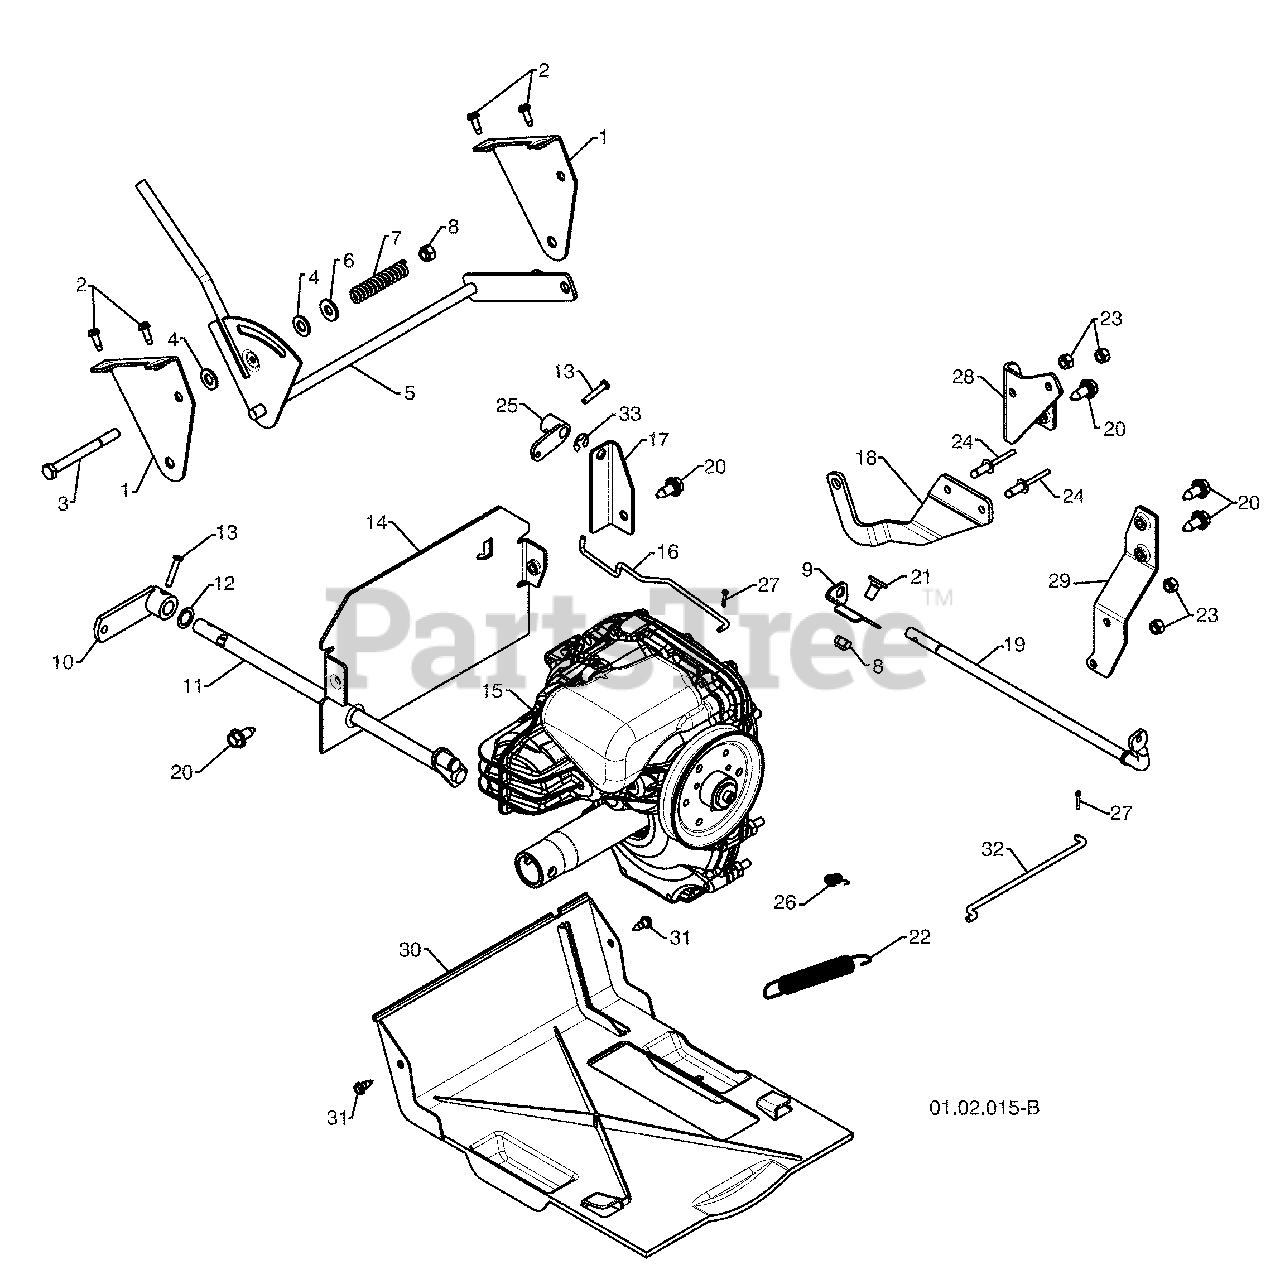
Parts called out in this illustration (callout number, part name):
1	SHIFT BRACKET
2	SCREW 10-24 X .625
3	SCREW 5/16-18 X 3.25
4	PLASTIC WASHER
5	SHIFT ASSEMBLY
7	FRICTION SPRING
8	NUT 5/16-18
9	FRONT CLUTCH BRACKET
10	CONTROL ARM
11	CONTROL SHAFT
13	CLEVIS PIN
14	REAR PLATE
15	TRANSMISSION
17	REAR CLUTCH BRACKET
18	CONTROL ARM
19	CLUTCH SHAFT
20	SCREW 5/16-18 X .750
21	CARRIAGE BOLT 5/16-18 X .625
22	BRAKE SPRING
23	NUT 1/4-20
24	POP RIVET 1/4 X .475
25	CLUTCH ARM
26	TRACTION SPRING
27	RETAINER CLIP
28	ANTI-ROTATE BRACKET
29	TORQUE STRAP BRACKET
30	BOTTOM PAN
31	SCREW 10-24 X .625
32	CLUTCH ROD
33	E-RING .375
